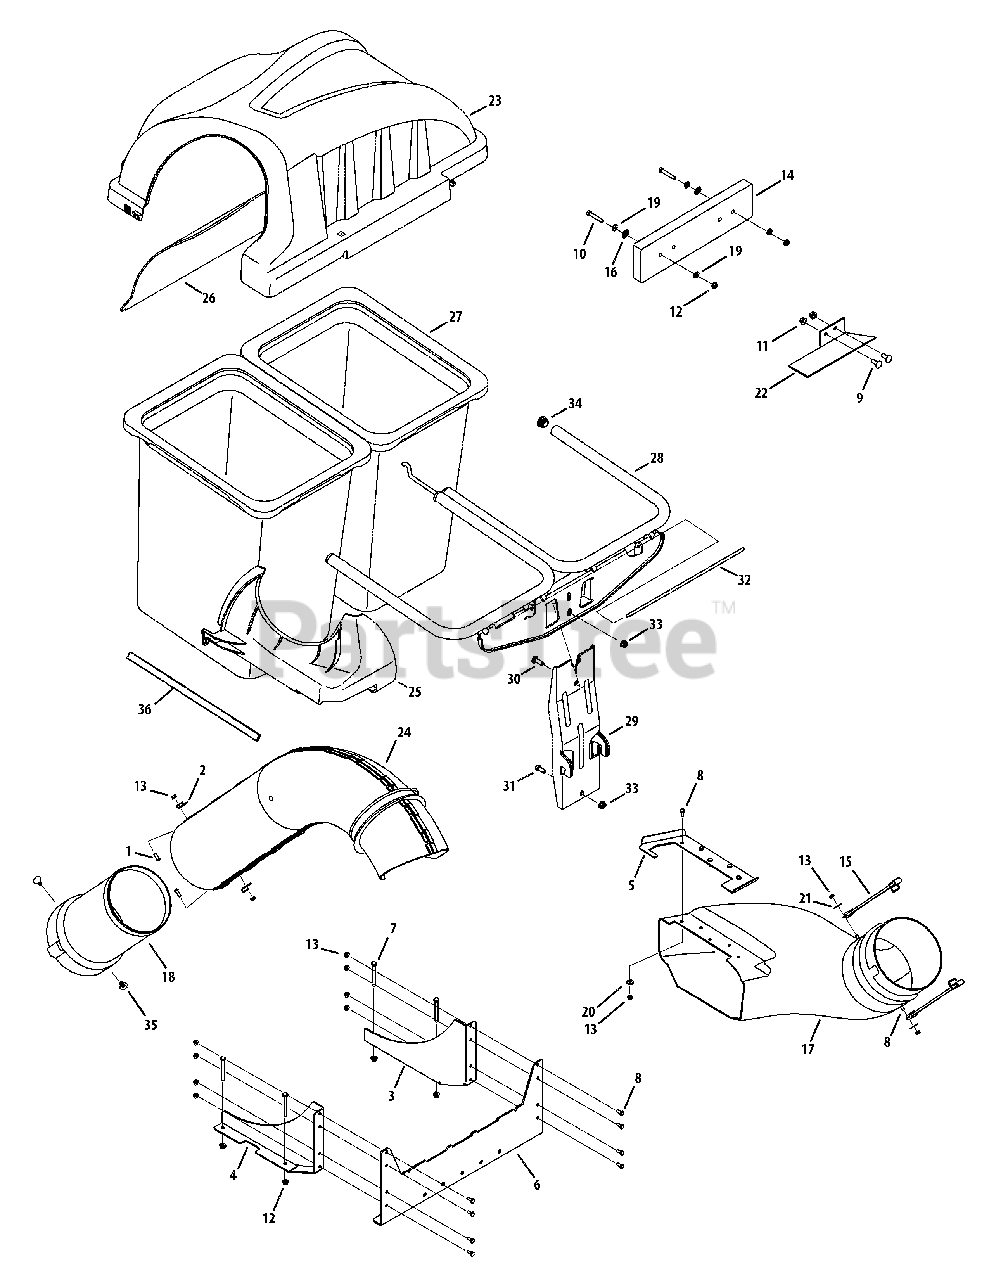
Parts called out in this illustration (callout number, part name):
1	Cap Screw, 1/4-20 x 750
2	Retainer Hook Bracket
3	Mount Assembly, RH
4	Mount Assembly, LH
5	Boot Mount Bracket
6	Catcher Mounting Bracket
7	Hex Head Screw, 5/16-18 x 275
8	Hex Head Screw, 1/4-20 x 620
9	Carriage Bolt, 3/8-16 x 100
10	Hex Head Screw, 5/16-18 x 200
11	Flange Lock Nut, 3/8-16
12	Flange Lock Nut, 5/16-18
13	Flange Lock Nut, 1/4-20
15	Chute Strap
16	Push Nut, 5/16
17	Discharge Chute Elbow
18	Chute Adapter
19	Flat Washer, 375 x 738 x 063
20	Belleville Washer
21	Flat Washer, 265 X 10 X 030
22	Baffle
23	Twin Bagger Cover Assembly
24	Upper Chute Assembly
25	Upper Chute Support
26	Bagger Cover Screen
27	Grass-bag Assembly
28	Twin Bag Support Assembly
29	Vertical Support Bracket
30	Carriage Screw, 5/16-18 x 100"
31	Hex Head Screw, 5/16-18 x 75"
32	Cover Hinge Pin
33	Flange Lock Nut, 5/16-18
34	End Plug
35	Ratchet Clip
36	Foam Strip
